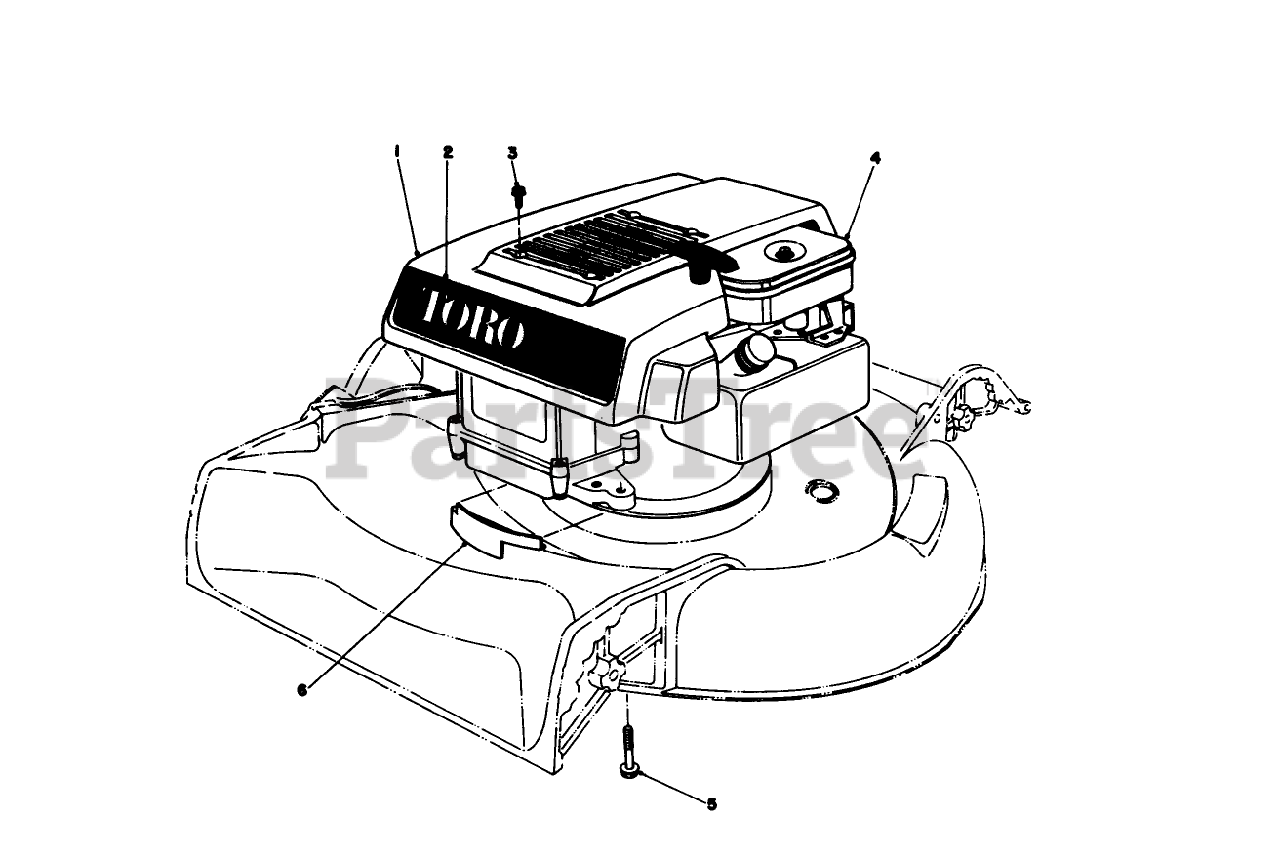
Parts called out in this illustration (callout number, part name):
1	SHROUD
2	Decal-Toro
3	8X1/2 SELF TAP SCREW
4	Engine (Model No. 16009)
5	Screw
6	HOUSING CAP
